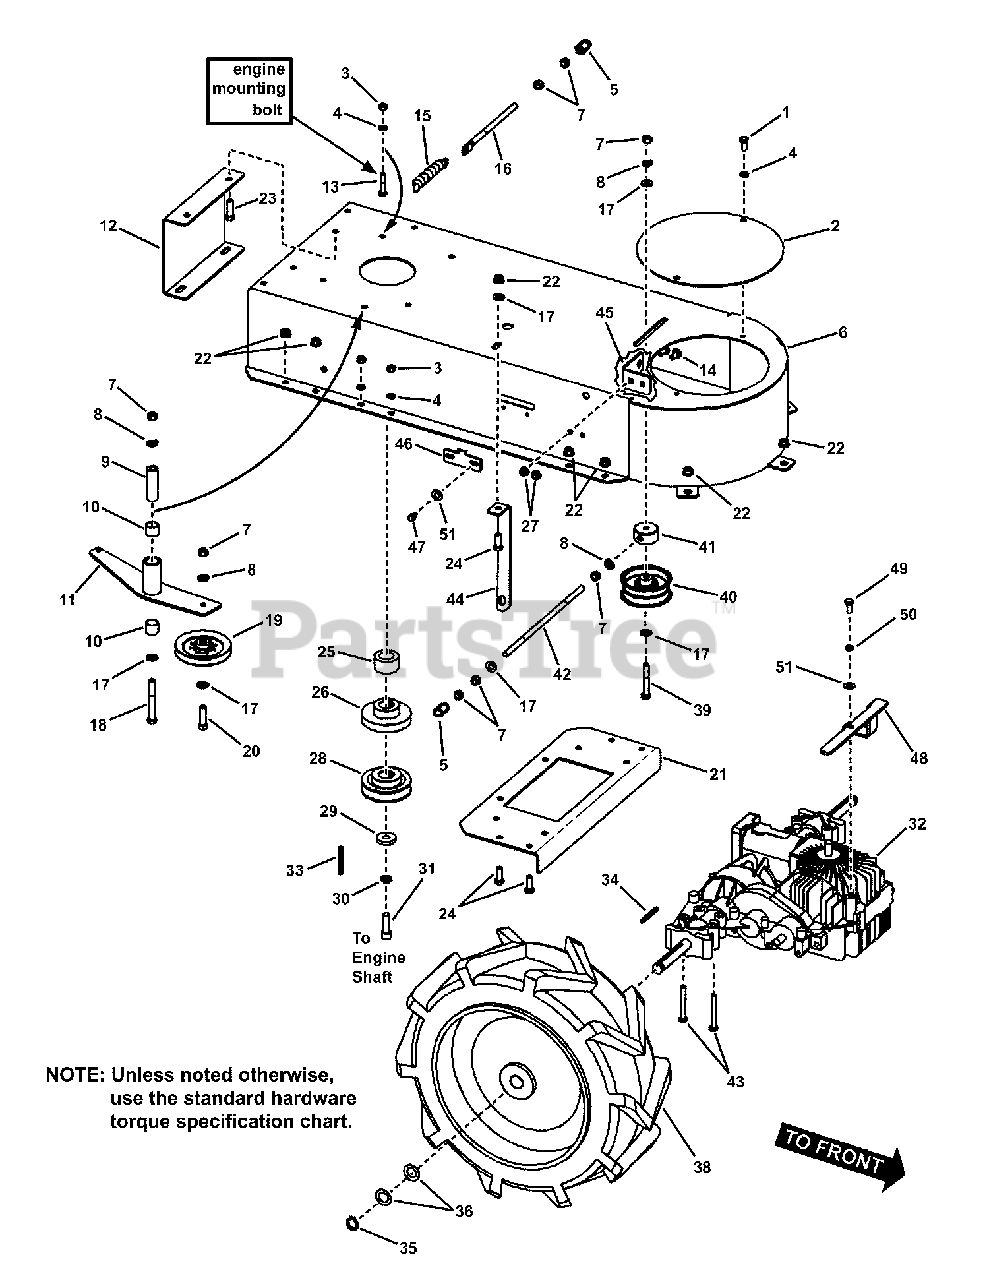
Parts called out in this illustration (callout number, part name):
1	SCREW, 5/16-18 x 3/4" Hex Head Cap, GR 5
2	PLATE, Clutch Cover
3	NUT, 5/16-18 Hex, GR 5 or B
4	WASHER, 5/16" Split Lock
5	CAP, Black
6	DECK, Engine (weldment)
7	NUT, 3/8-16 Hex, GR 5 or B
8	WASHER, .38 x .68 x .09 Split Lock
9	BOSS, Idler Arm Pivot
10	SLEEVE BUSHING, 3/4 ID
11	IDLER ARM, Transmission (weldment)
12	COVER, Engine Back
13	SCREW, 5/16-18 x 1-1/2" Hex Head Cap, GR 5
14	BOLT, 5/16-18 x 3/4" Short Neck Carriage, GR 5
15	SPRING, Idler
16	ROD, Idler Tension (3/8-16 thread)
17	WASHER, 3/8 SAE Flat
18	SCREW, 3/8-16 x 3-1/4" Hex Head Cap
19	PULLEY, Idler
20	SCREW, 3/8-16 x 1-3/4" Hex Head Cap, GR 5
21	PLATE, Lower Handle Mount
22	NUT, 3/8-16 Hex Flange Lock
23	SCREW, 3/8-16 x 1-1/4" Hex Head Cap, GR 5
24	SCREW, 3/8-16 x 1 Hex Head Cap, GR 5
25	SPACER, Engine Shaft
26	PULLEY, Blade Clutch Drive
27	NUT, 5/16-18 Hex Flange Lock, GR 5
28	PULLEY, Trans. Drive
29	WASHER, .468 x 1-3/8 x 1/4" Flat
30	WASHER, 7/16" Split Lock
31	CAPSCREW, 7/16-20 x 1-12" Socket Head
32	TRANSAXLE
33	KEY, 1/4 Square x 2-1/8" (engine shaft)
34	KEY, 3/16 Square x 2-3/16"
35	RETAINING RING, 3/4" External
36	WASHER, 3/4 I.D. Thrust
38	DRIVE WHEEL, Right
39	SCREW, 3/8-16 x 2-1/2" Hex Head Cap, GR 5
40	PULLEY, Blade Clutch Idler
41	IDLER BOSS
42	ROD, Blade Clutch Idler Tensioning (3/8-16 thread)
43	SCREW, 5/16-18 x 2-1/4" Hex Head Cap, GR 5
44	HANGER, Trans. Forward Mount
45	BRACKET, Clutch Support
46	PLATE, Lock Engage
47	SCREW, 1/4-20 x 3/4" Hex Washer Self-Tap
48	BRACKET, Lock Lever (weldment)
49	SCREW, 1/4-28 x 5/8" Hex Head Cap, GR 8
50	WASHER, 1/4" Split Lock
51	WASHER, .28 x .63 x .06 Flat
